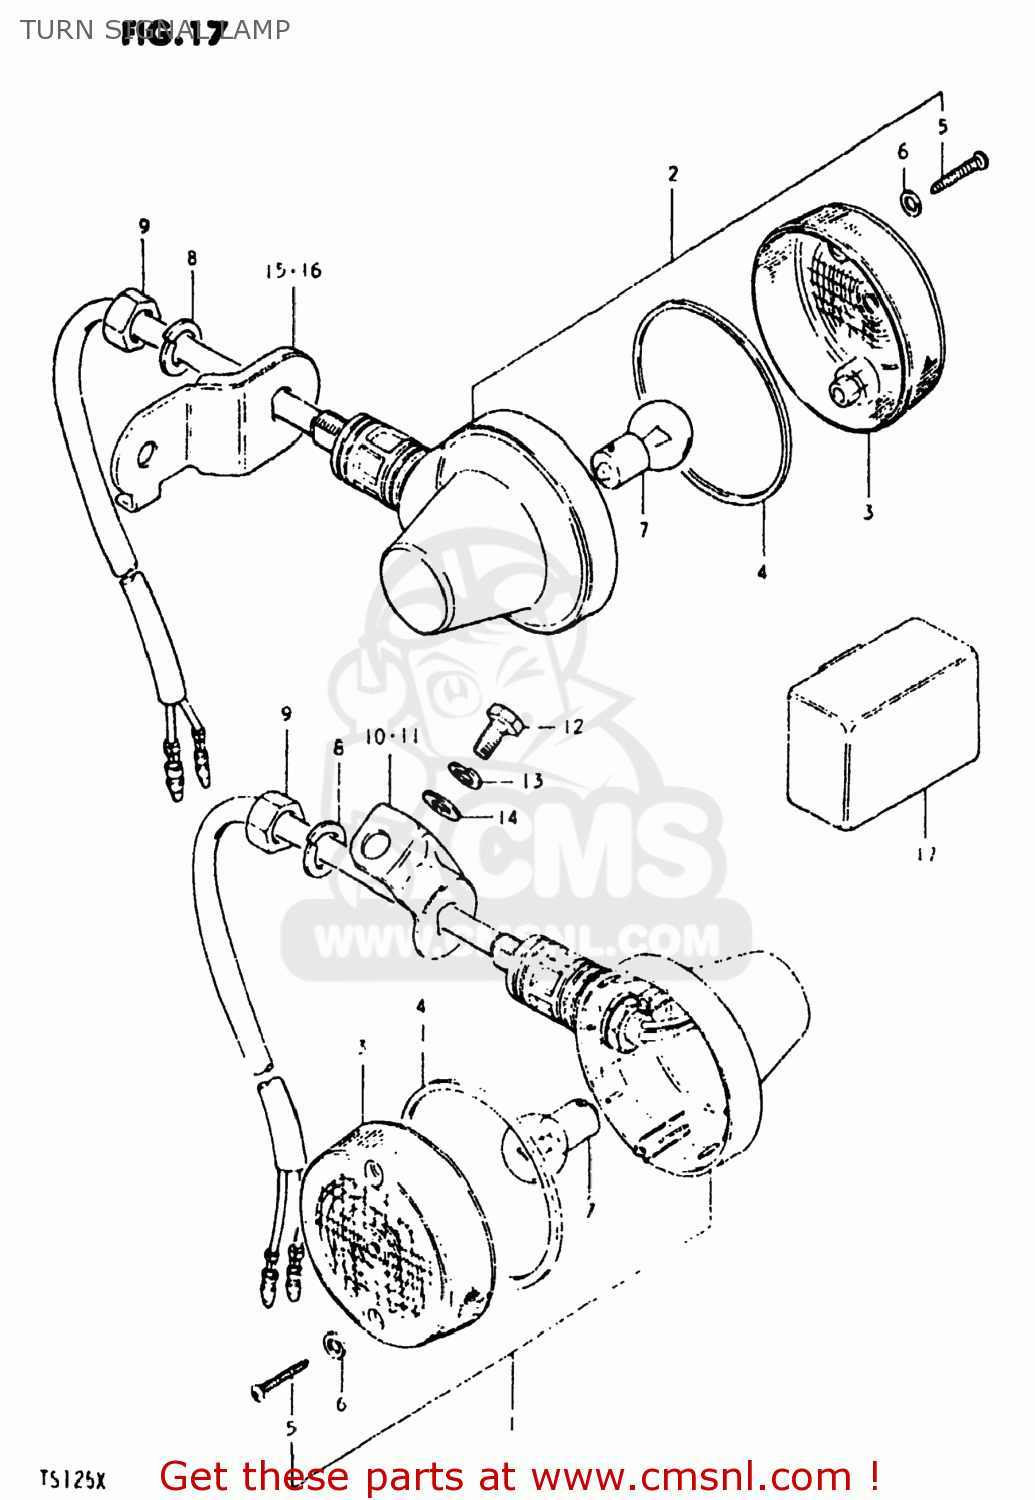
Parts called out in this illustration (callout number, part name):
1	LAMP ASSY,RR TURNSIGNAL
2	LAMP ASSY,RR TURNSIGNAL
3	LENS
4	GASKET (NAS)
5	SCREW TAPP.
6	GASKET (NAS)
7	BULB(6V17W,STANLEY,A4513A)
8	WASHER,LOCK 12
9	NUT
10	BRACKET,TURNSIGNAL LAMP,R
11	BRACKET,TURNSIGNAL LAMP,L
12	BOLT
13	LOCK WASHER
14	WASHER
15	BRACKET,REAR TURN SIGNAL
16	BRACKET,REAR TURN SIGNAL
17	RELAY,TURN SIGNAL
